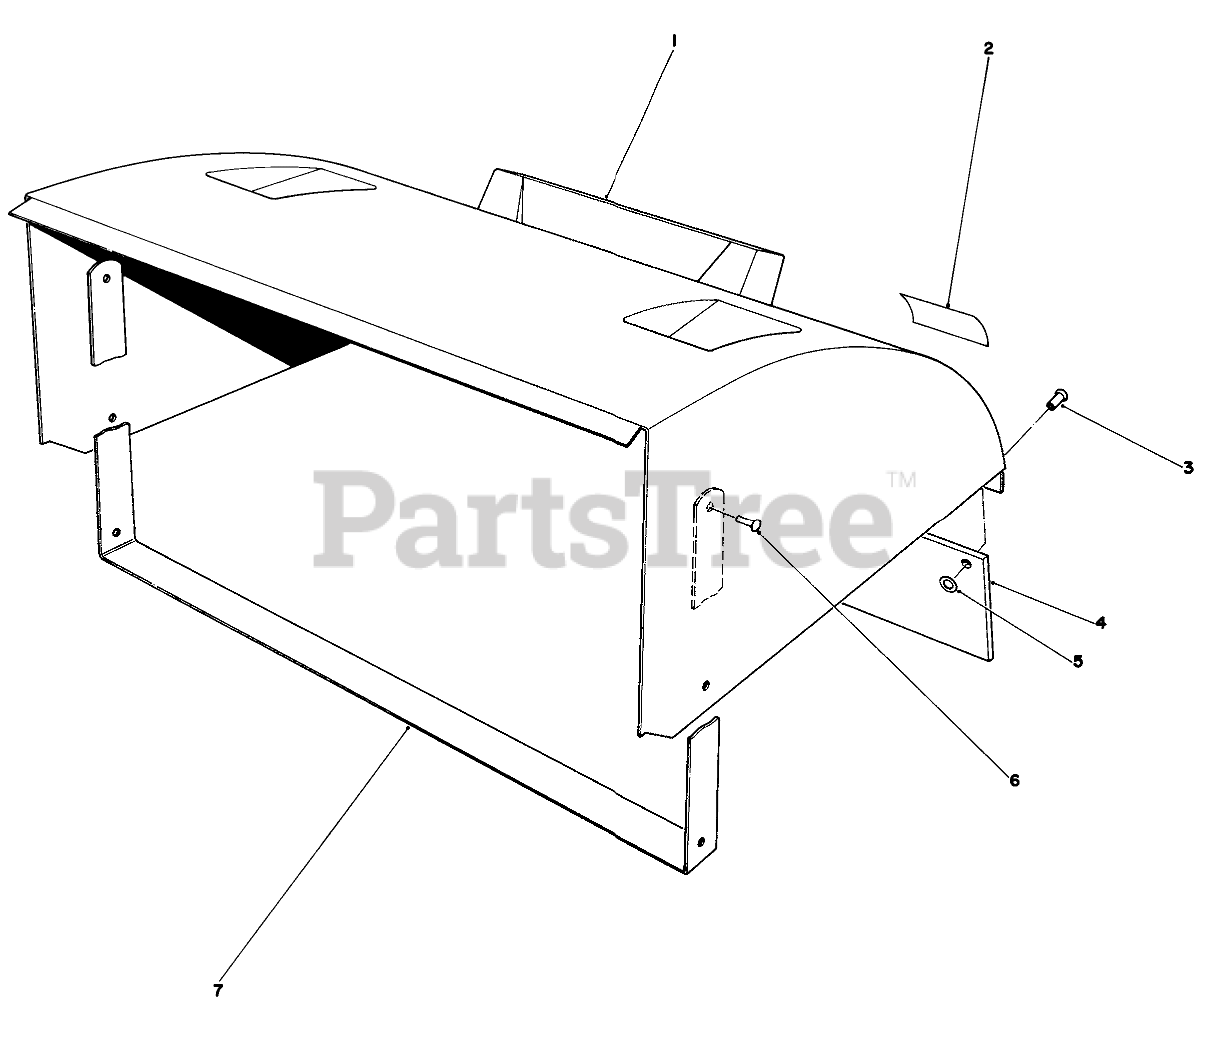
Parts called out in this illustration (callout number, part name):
1	Deflector-Grass
2	Decal Danger
3	.185 DIA X .375 RT +
4	Flap-Deflector
5	WASHER-FLAT
6	RIVET
7	Bracket-Grass Deflector
